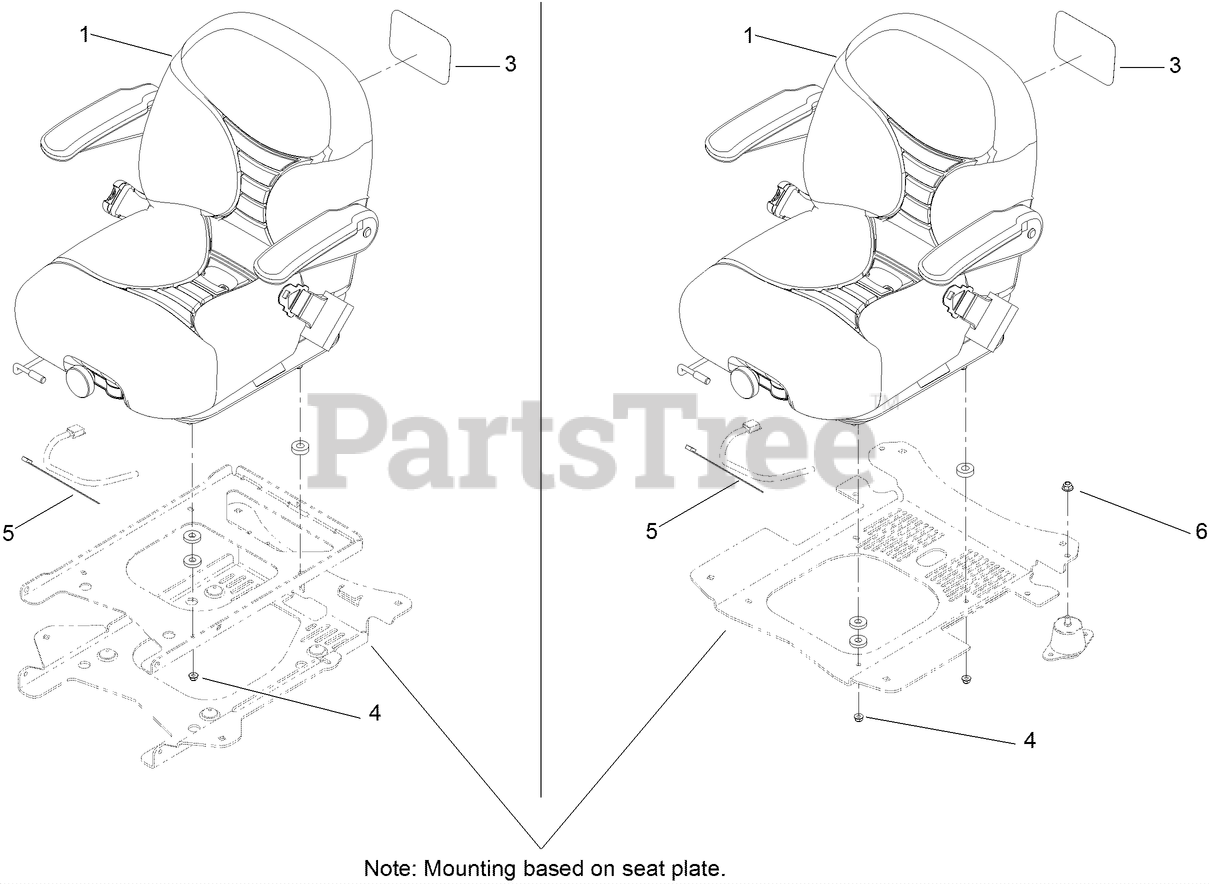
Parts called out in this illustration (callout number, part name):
1	SUSPENSION SEAT ASM
3	DECAL
4	NUT-HF
5	TIE-PLASTIC
6	NUT-HF, NI
